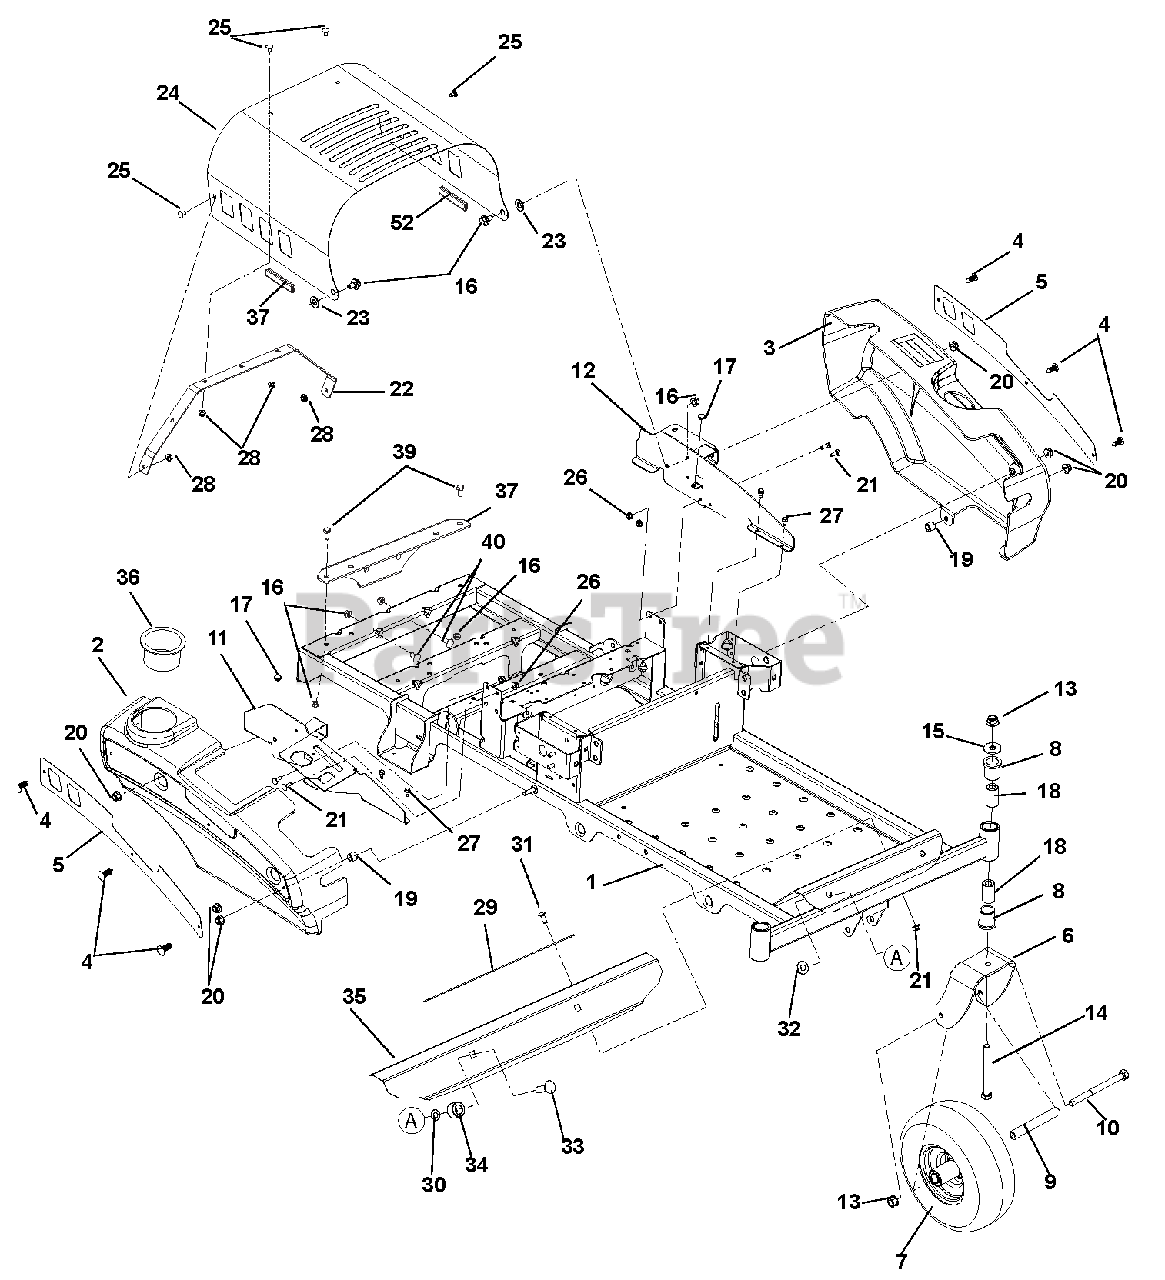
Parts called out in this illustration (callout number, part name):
1	WMT, FRAME ZOOM/ZT
2	FENDER, RH
3	FENDER, LH
4	RIVET, .25 NYLON PANEL
5	PLATE, FENDER
6	WMT, CASTER FORK
7	TIRE/WHL ASM, FRONT
8	BSHG-FLG 1.00X1.25X1.50X1.50
9	SPACER, ROLLED WHEEL
10	@BLT-HEX .50-13X6.50 GR5 YWZC
11	WMT-RH FENDER MOUNT
12	WLDMNT, LH FENDER MOUNT
13	@NUT-LK-TOP-FLG .50-13 YWZC
14	@BLT-HEX .50-13X5.00 GR5 YWZC
15	WSHR-FL-STL.511X1.441X.125 YWZ
16	BOLT-SHLDR .375-16X.150
17	BUMPER GROMMET
18	SPACER, CASTER .50X1.00X1.84
19	BSHG-SLV .391X.688X.52 PM
20	@NUT-LK-NYL-FLG .31-18 YWZC
21	@BLT-RDHDSQNK .25-20X.75 G5YZ
22	BRACE, HOOD
23	WSHR-FL-NYL .518X1.000X.080
24	HOOD, ZOOM
25	@BLT-RDHDSQNK .25-20X.50 G5YZ
26	@NUT-LK-NYL-FLG .25-20 YWZC
27	@SCR-TAP .25-20X.50 HWH TR YWZ
28	@NUT-LK-TOP-FLG .25-20 YWZC
29	GRIP, ADHESIVE (1" X 16" BLK)
30	NUT-PUSH, .50
31	@BLT-RDHDSQNK .31-18X.75 G5YZ
32	@NUT-LK-NYL-FLG .50-13 YWZC
33	@BLT-RDHDSQNK .50-13X1.75 G5YZ
34	TUBE, UPPER CONTROL PIVOT
35	FOOTREST
36	CUPHOLDER, SNAP-IN 3.75OD
37	EDGING, CLUTCH PADDLE - 2.00"
38	PLATE, BBZ HITCH KIT PLATE
39	@BLT-HEX .38-16X.75 GR5 YWZC
40	@BLT-RDHDSQNK .38-16X.75 G5YZ
